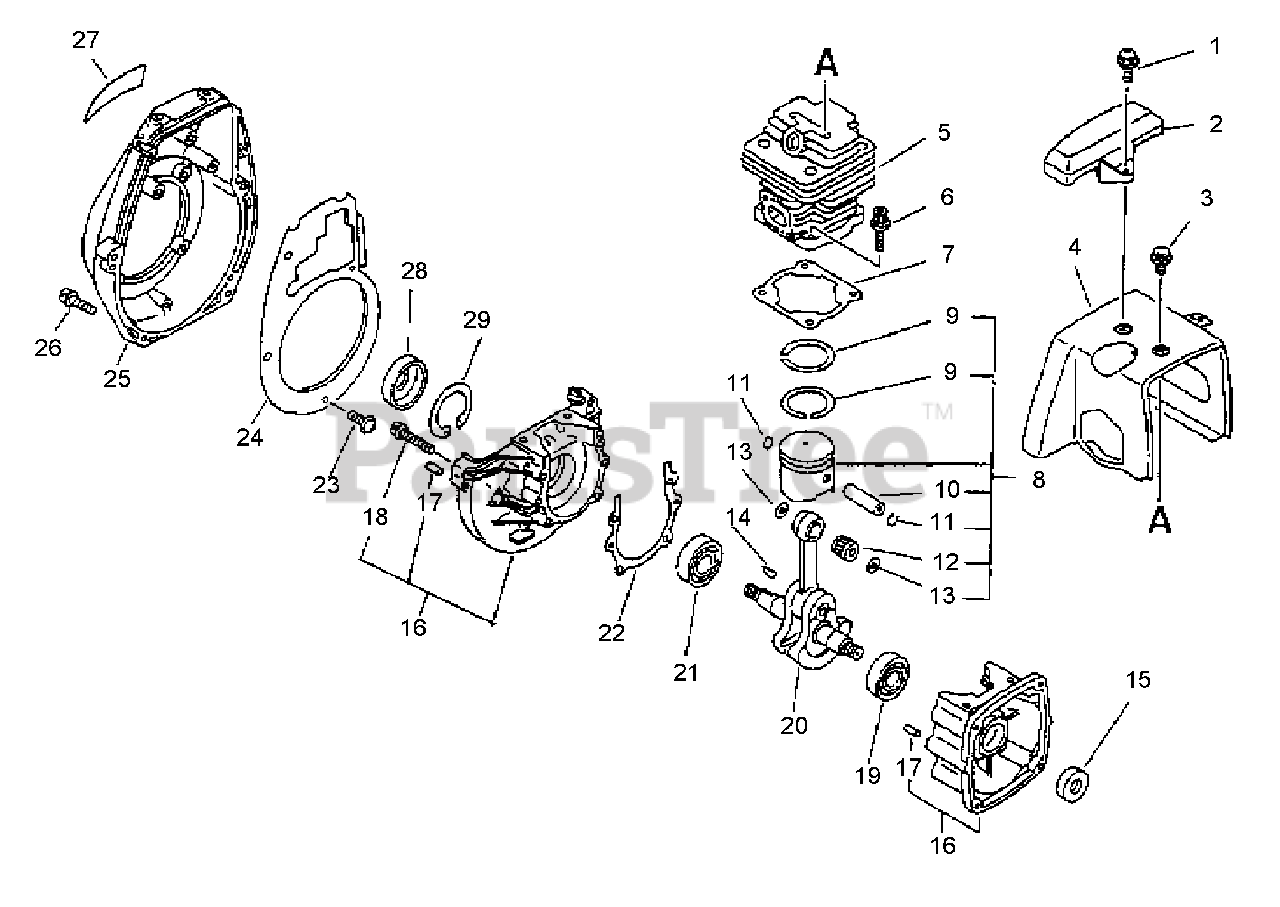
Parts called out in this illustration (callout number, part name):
1	SCREW - 5X14
2	GUARD - TOP
3	SCREW - 5X10
4	COVER, ENGINE - GRAY
5	CYLINDER
6	SCREW - 5X20
7	GASKET, CYLINDER
8	PISTON KIT
9	RING, PISTON
10	PIN, PISTON
11	RING, RETAINING - 8
12	BEARING, NEEDLE
13	SPACER, PISTON
15	SEAL, OIL - 12
16	CRANKCASE KIT
17	PIN - LOCATING
18	SCREW - 5X30
19	BEARING, BALL - 6201
20	CRANKSHAFT ASSY
21	BEARING, BALL - 6202
22	GASKET, CRANKCASE
23	SCREW - 4X10
24	SHIELD, FAN
25	CASE, FAN
26	SCREW - 5X25
27	LABEL - MODEL
28	SEAL, OIL
29	RING, RETAINING - 35
